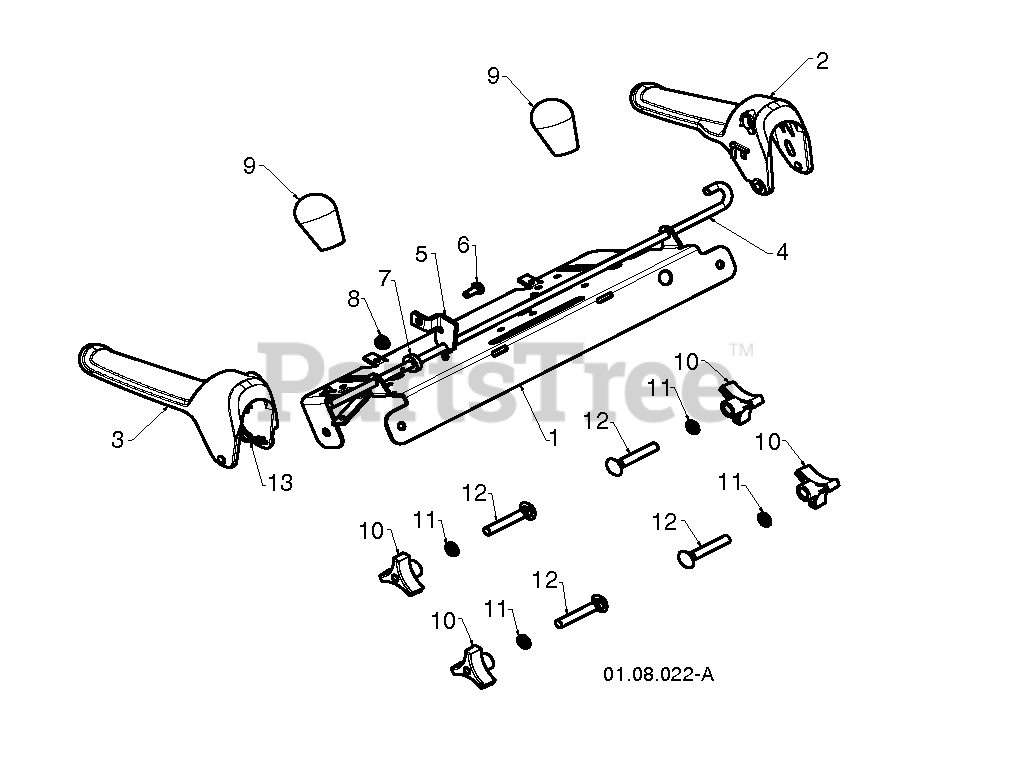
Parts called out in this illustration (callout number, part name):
1	PANEL.CONTROL.SNOW.BLACK
2	LEVER.CONTROL.LH.PL.BLACK
3	LEVER.CONTROL.RH.PL.BLACK
4	BAIL.CONTROL.INTERLOCK.SNOW
5	BRACKET.ARM.IMPELLER.ROD.YZ
6	BOLT
7	SPACER.CONTROL.LEVER
9	KNOB.OVERMOLD.DS.HUSQVARNA/BLK
10	KNOB.HANDLE.3/8.TRI-POINT.BLAC
11	WASHER
12	BOLT 3/8-16 X 2-1/4
13	SPRING RETAINER
